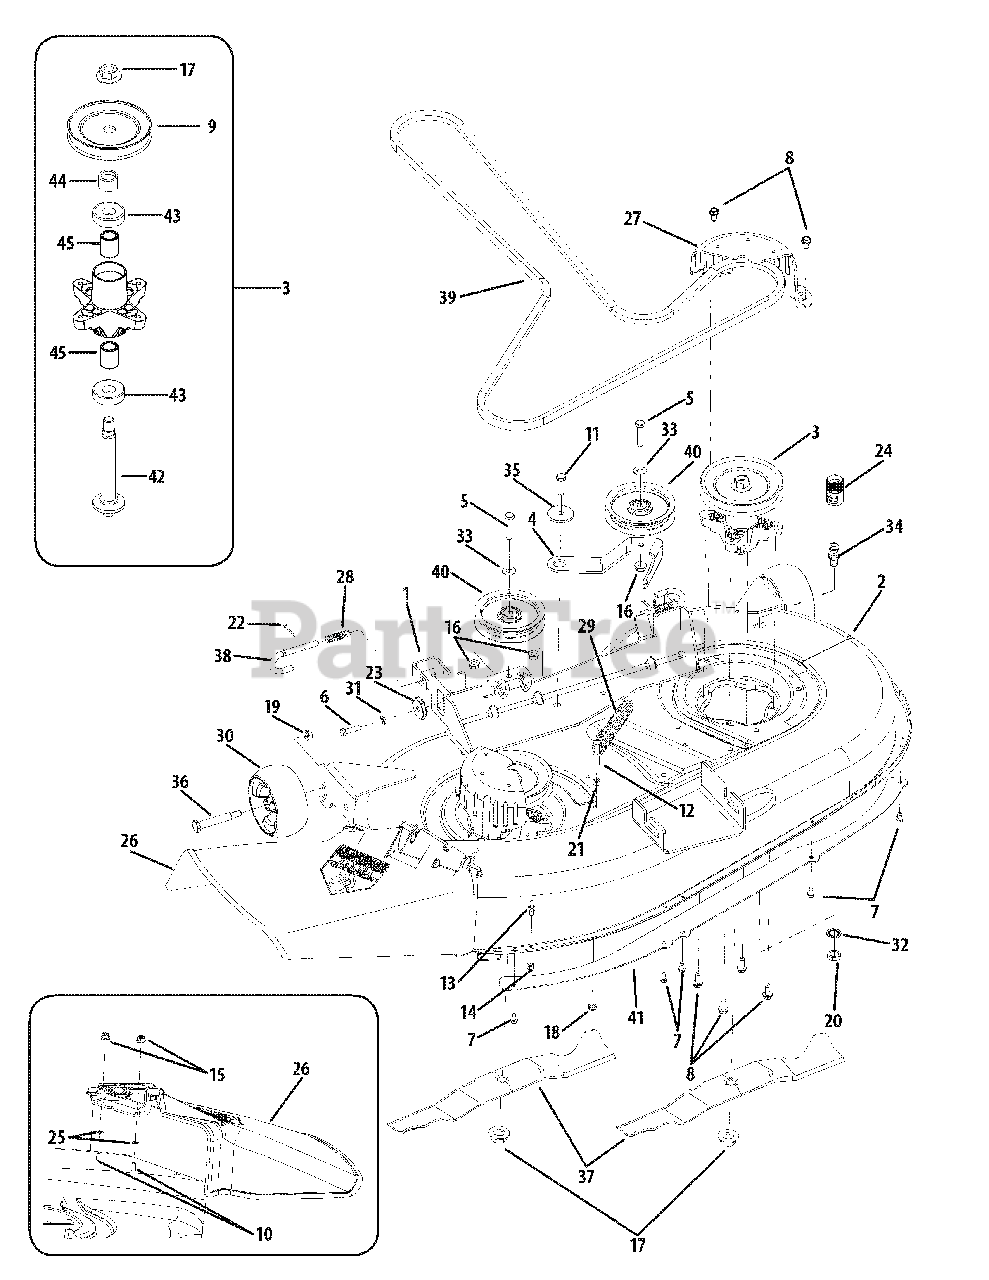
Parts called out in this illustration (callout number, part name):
1	Deck Lift Bracket
2	Deck Housing
3	Spindle Assembly
5	Hex Cap Screw, 3/8-16 x 1.75
6	Hex Cap Screw, 5/16-18 x 1.25
7	Hex Washer Head Screw, 1/4-20 x .5
8	Hex Washer Head Screw, 5/16-18 x .750
9	Pulley
10	Hex Cap Screw, 1/4-20 x .62
11	Hex Cap Screw, 3/8-16 x 1.25
12	Hex Cap Screw, 5/16-18 x 1.75
13	Grass Catcher Pin, 1/4-20
14	Hex Insert Lock Nut, 1/4-20
15	Hex Insert Flange Lock Nut, 1/4-20
16	Hex Insert Flange Lock Nut, 3/8-16
17	Hex Flange Nut, 5/8-18
18	Hex Insert Lock, 5/16-18
19	Hex Flange Lock Nut, 3/8-16
20	Hex Nut, M16-1.5
21	Hex Nut, 5/16-18
22	Cotter Pin, 1/8 x 1.25
23	Deck Adjustment Gear
24	Water Nozzle Adapter
25	Push Nut, .25 x .5
26	Discharge Chute Assembly
27	Belt Cover
28	Compression Spring, .535 x 1.751
29	Extension Spring, .94 Dia. x 6.74
30	Deck Ball Wheel, 5.0
31	Lock Washer, 5/16
32	Lock Washer
33	Flat Washer, .38 x .93 x .11
34	Deck Water Nozzle
35	Shoulder Spacer, .884 x .19
36	Shoulder Screw, .5 x 2.5 x 3/8-16
37	Blade, 3 in 1, 21.23
38	Deck Hanger Rod
39	V-Belt
40	Idler Pulley, 4.25 Dia
41	Deck Skirt
42	Spindle Shaft, 5.75
43	Ball Bearing
44	Spacer, .820 x 1.15 x .73
45	Spacer, .8 x 1.10 x 1.322
